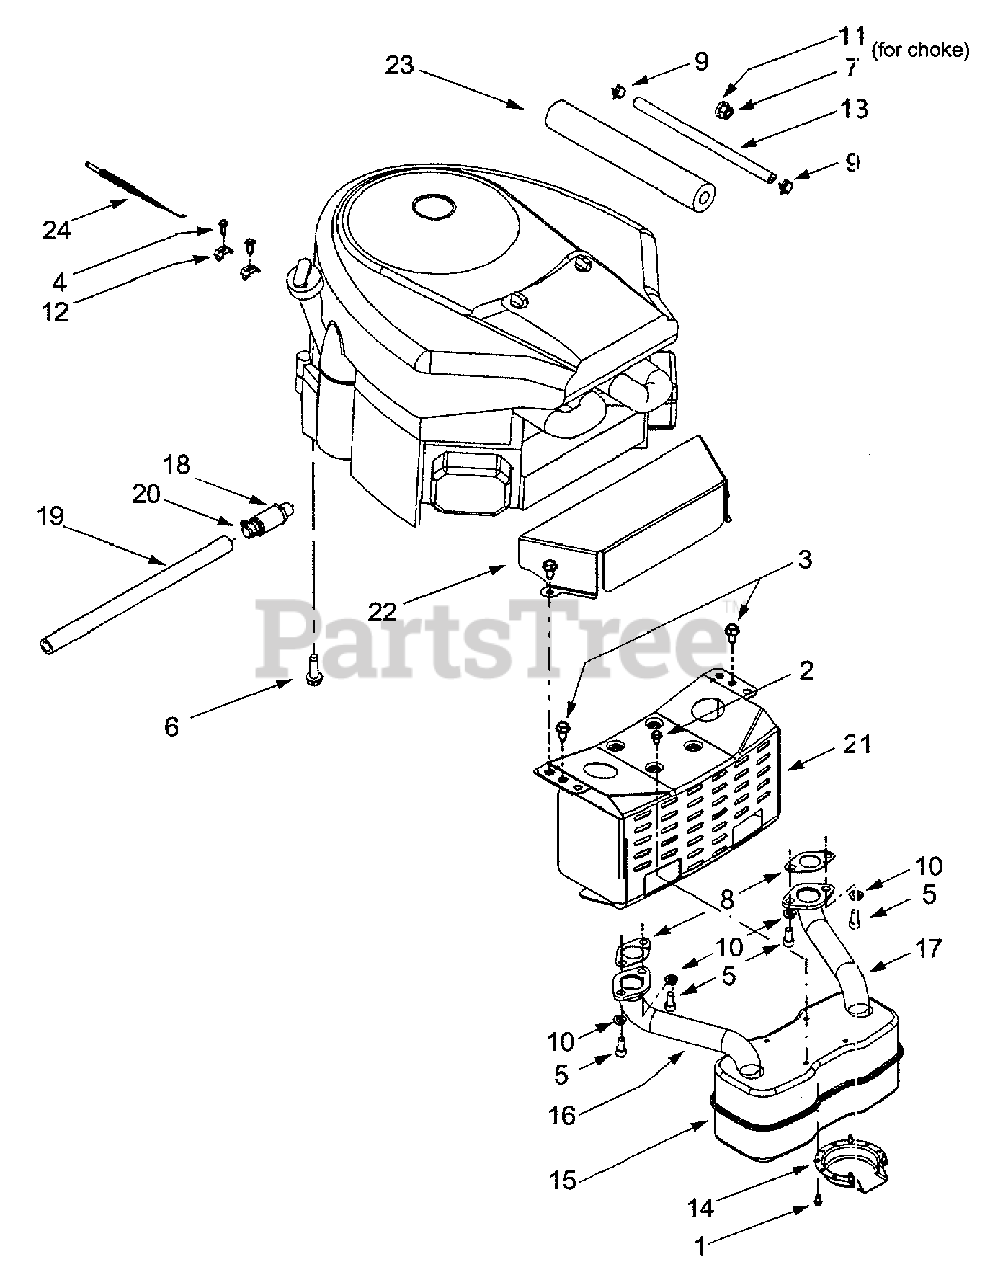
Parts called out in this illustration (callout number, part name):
1	Self-tapping Screw, #8-18 x.5
2	Self-tapping Screw, 1/4-20 x .5
3	Self-tapping Screw, 5/16-18 x .625
4	Hex Screw, #10-32 x .625
5	Socket Cap Screw, 5/16-18 x .625
6	Self-tapping Screw, 3/8-16 x 1.25
7	Hex Nut, 3/8-16
8	Exhaust Gasket
9	Hose Clamp
10	Lock Washer, 5/16
11	Flat Washer
12	Casing Clamp
13	Fuel Line Hose
14	Muffler Deflector
15	Muffler, Twin Inlet
16	RH Exhaust Pipe
17	LH Exhaust Pipe
18	Oil Drain Valve
19	Oil Drain Hose
20	Oil Drain Cap
22	Engine Heat Shield
23	Foam
24	Throttle Cable
